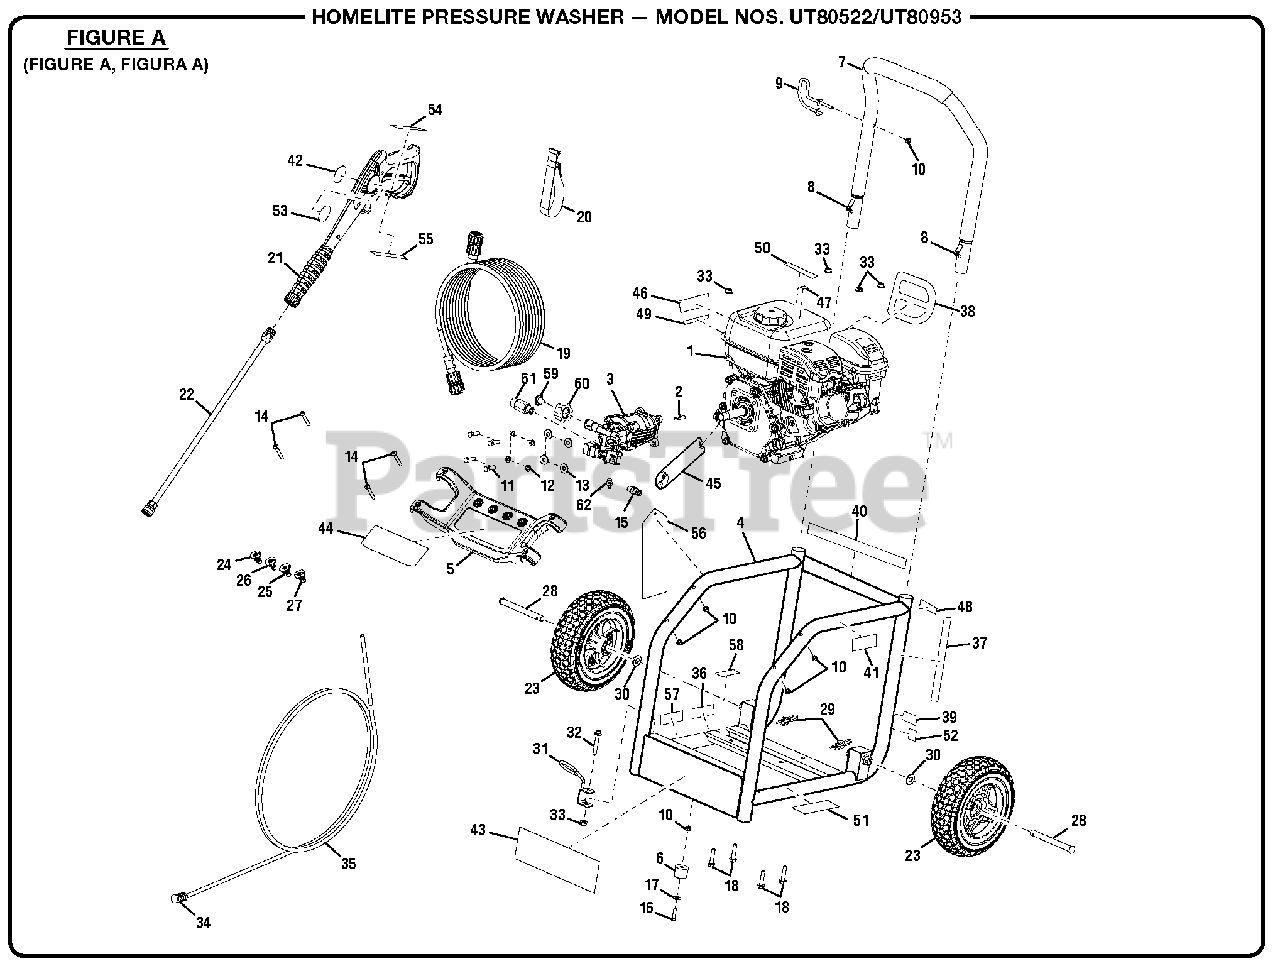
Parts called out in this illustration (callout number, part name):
2	Output Shaft Key (3/16 x 35 mm)
3	Pump
4	Main Frame
5	Nozzle Holder
6	Rubber Foot
7	Handle Assembly
8	Lock Button w/Spring Clip
9	Wand Holder (Upper)
10	Lock Nut (1/4-20)
11	Bolt (5/16-24 x 27 mm, Hex Hd.)
12	Lock Washer (5/16 in.)
13	Washer (5/16 in.)
14	Screw (1/4-20 x 2.0 in., Torx)
15	Thermal Release Valve
16	Bolt (1/4-20 x 1-1/4 in.)
17	Washer (1/4 in.)
18	Bolt (M8 x 40 mm, Hex Flange Hd.)
20	Hook and Loop Strap
21	Trigger Handle
22	Extension Wand
23	Wheel Assembly (10 in. x 3 in.)
24	Nozzle, 0deg
25	Nozzle 40deg
26	Nozzle 25deg
27	Soap Nozzle
29	Hitch Pin
30	Washer (1/2 in.)
31	Wand Holder (Lower)
32	Bolt (M8 x 50 mm, Flange Hd.)
33	Lock Nut (M8 x 1.25)
35	Chemical Siphon Tube
36	Pump Start Label
37	Engine Start Label
38	Recoil Label
39	Choke Label
40	Data Label
41	Hot Surface Label
42	Trigger Handle Logo Label
43	Homelite Label
44	Performance Label
45	Add Oil Label
46	Danger Label
47	E85 Label
48	Homelite Inquiries Label
49	EMC Compliance Label
50	No Oil to Gas Label
51	Combustion Label
52	Fuel Label
53	Trigger Handle Warning Label (French and Spanish)
54	Warning Label (English)
55	Wand Label (Max Rating)
56	Danger Hangtag
57	Lubricant Label
58	Dip Stick Label
59	Filter Screen
60	Inlet Tube
61	Outlet Tube
62	Detergent Suction Kit
